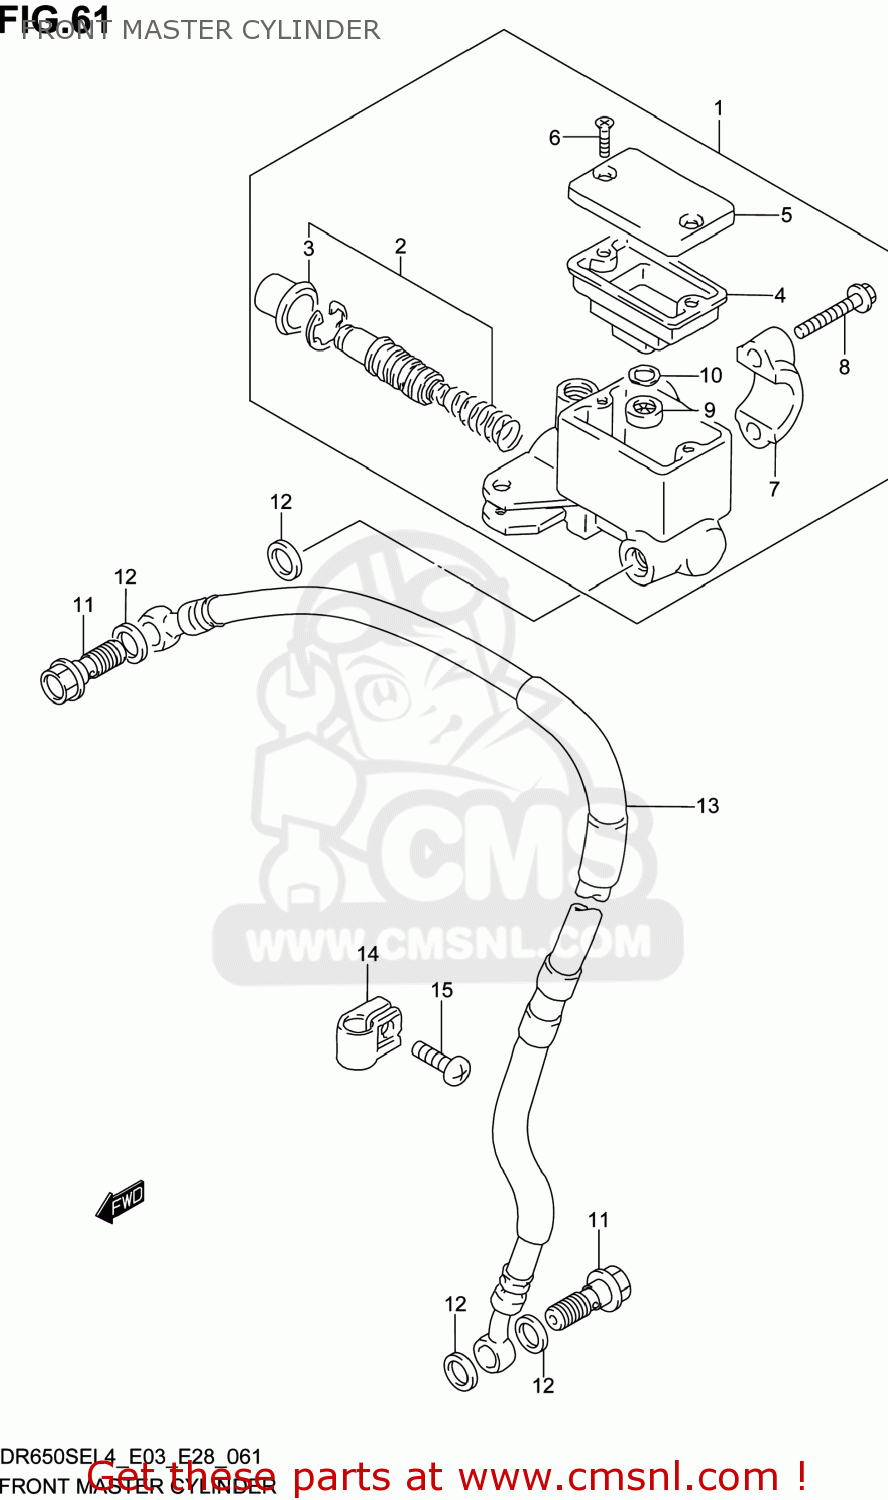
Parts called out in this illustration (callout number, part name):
1	CYLINDER ASSY,FR MASTER
2	PISTON/CUP SET
3	BOOT
4	DIAPHRAGM
5	CAP
6	SCREW
7	HOLDER
8	BOLT(6X22)
9	SEPERATOR
10	PLATE
11	BOLT UNION
12	WASHER(10X15X1.5)
13	HOSE,FR BRAKE
14	CLAMP,BRAKE HOSE
15	SCREW
